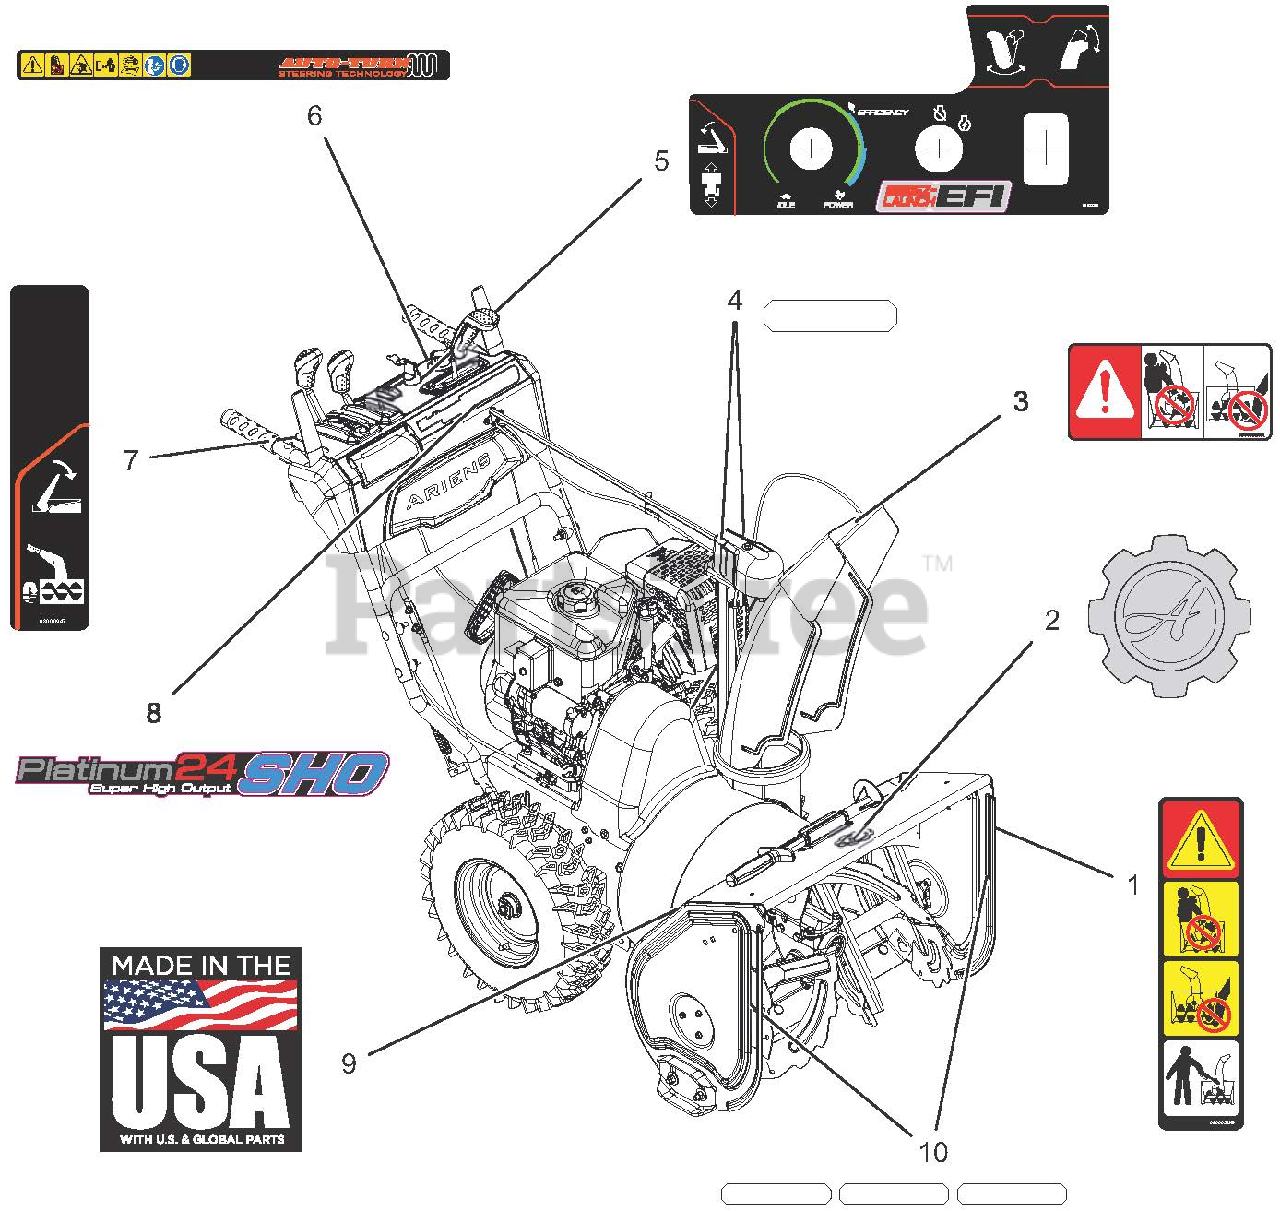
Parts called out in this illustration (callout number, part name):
1	DECAL, DANGER - ROTATING PARTS
2	DECAL, ARIENS-GEAR BADGE
3	DECAL, DANGER
4	DECAL,REFLECTIVE,GEAR COVER
5	DECAL, CONTROL - QT EFI W/GEL
6	DECAL,DASH - SAFETY/EFI
7	DECAL,CONTROL-RH CONTROL
8	DECAL, DASH, PLATINUM 24 SHO
9	DECAL, MADE IN USA
10	DECAL,REFLECTIVE,HOUSING
